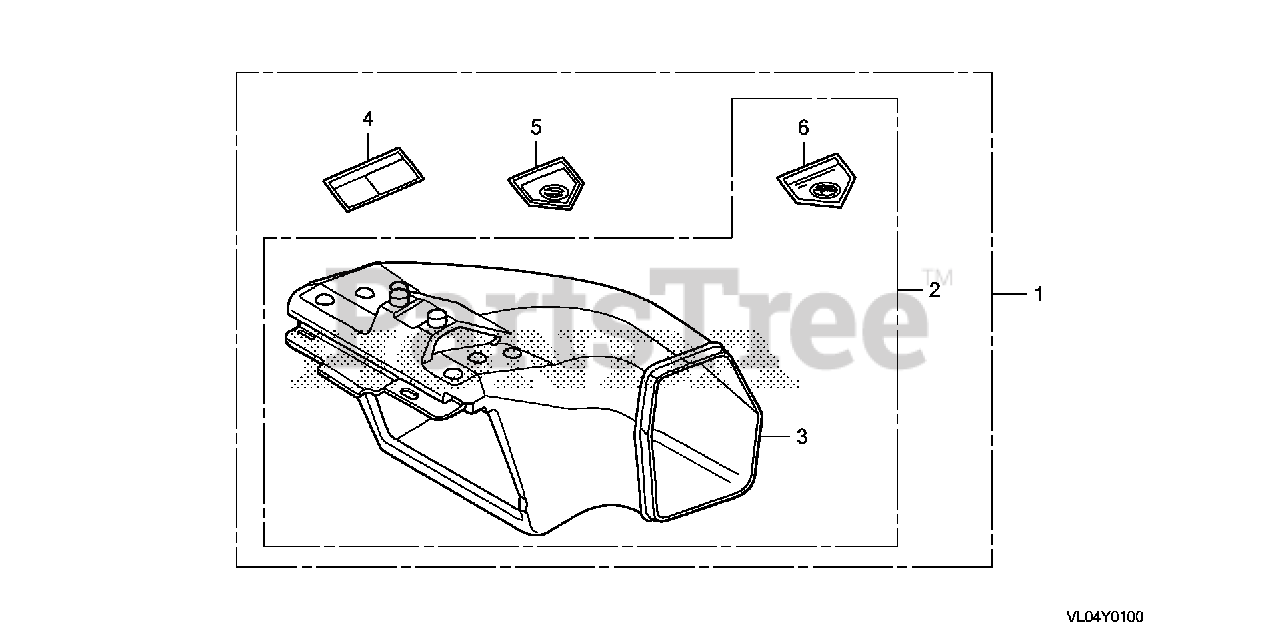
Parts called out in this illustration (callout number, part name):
2	CHUTE KIT, SIDE DISCHARGE
3	CHUTE KIT, SIDE DISCHARGE
6	CAUTION C, HOUSING
